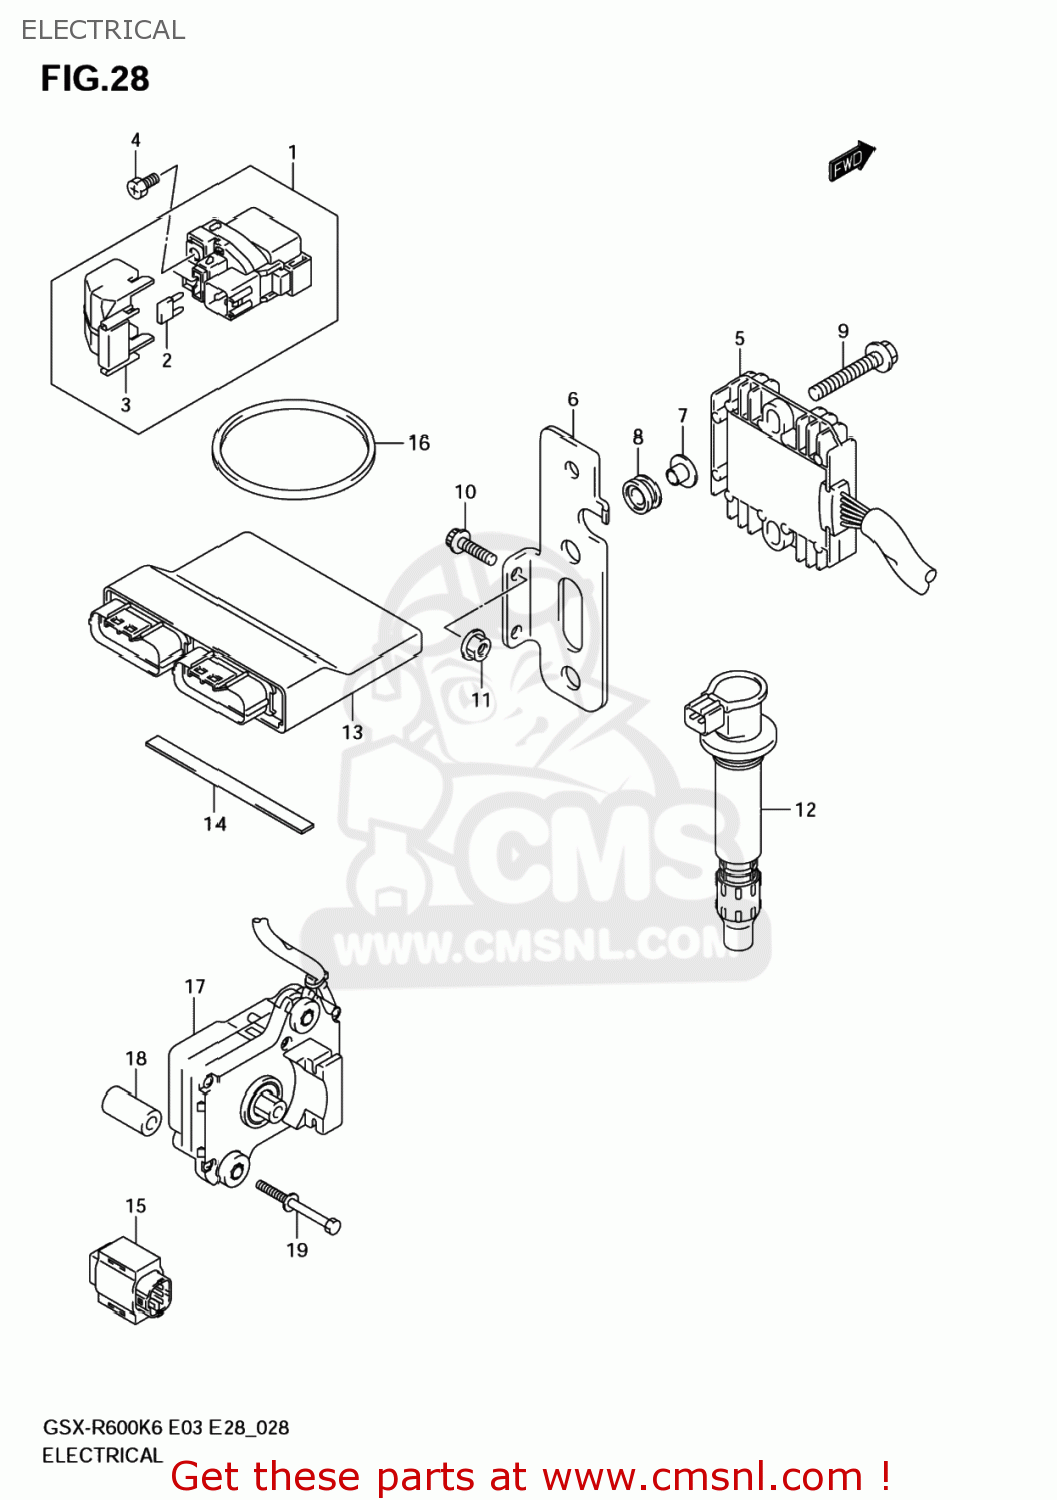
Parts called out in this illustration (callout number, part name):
1	RELAY ASSY,STARTING MOTOR
2	FUSE(30A)
3	COVER
4	SCREW(6X8)
5	RECTIFIER ASSY
6	BRACKET,RECT FIG
7	SPACER(6.2X8.4X6.9)
8	CUSHION
9	SCREW
10	BOLT
11	NUT
12	COIL ASSY,IGNITION
13	CONTROL UNIT,FI
14	CUSHION(130X10X2)
15	SENSOR ASSY,FUEL CUT
16	O RING(D:3.5,ID:76)
17	ACTUATOR ASSY,EXHAUST CONTROL
18	SPACER(6.2X14.5X26)
19	BOLT
